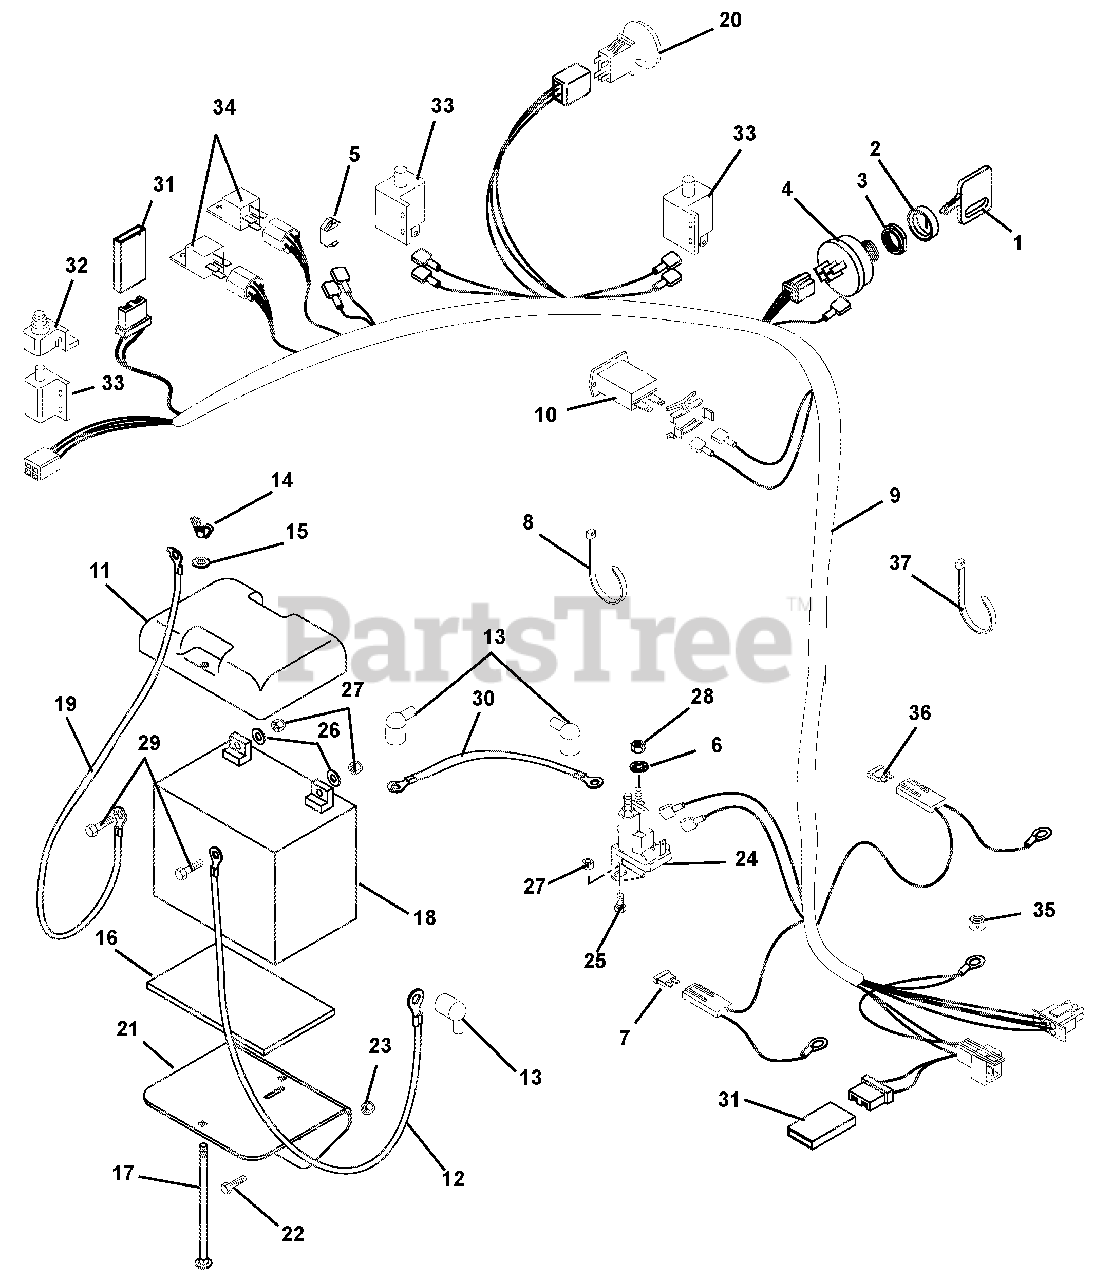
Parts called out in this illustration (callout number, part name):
1	Key- with Cap
2	Cap, Ignition Switch
3	Nut, Panel .625-32
4	Key Switch
5	Light, Indicator
6	Washer-Locking .31
7	Fuse-25 AMP
8	Tie Wrap-Black
9	Wire Harness
10	Hour Meter-Quartz
11	Cover-Battery
12	Cable, Positive Battery
13	Boot, Eyelet Terminal
14	Nut-Locking-Wing .25-20
15	Washer-Flat-Steel .281 x .625 x .065
16	Pad, Battery
17	Bolt-Round Head Square Neck .25-20 x 7.00 Grade 2
18	Battery, Filled
19	Cable, Negative Battery
20	Switch- PTO- NMIR
21	Weldment, Battery Tray
22	Bolt-Hex .38-16 x 1.75 Grade 5
23	Nut-Locking-Nylon .38-16
24	Solenoid
25	Bolt-Hex .25-20 x .50 Grade 5
26	Washer-Flat-Steel .281 x .62 x .065
27	Nut-Locking-Flange .25-20 (108, 109)
28	Nut- Jam .31-24
29	Bolt-Hex .25-20 x .75 Grade 5
30	Starter Cable 6.75"
31	Diode, Connector Shell
32	Boot, Rubber
33	Switch, Interlock
34	Relay
35	Nut-Locking-Top-Flange .31-18
36	Fuse-20 AMP
37	Tie Wrap
